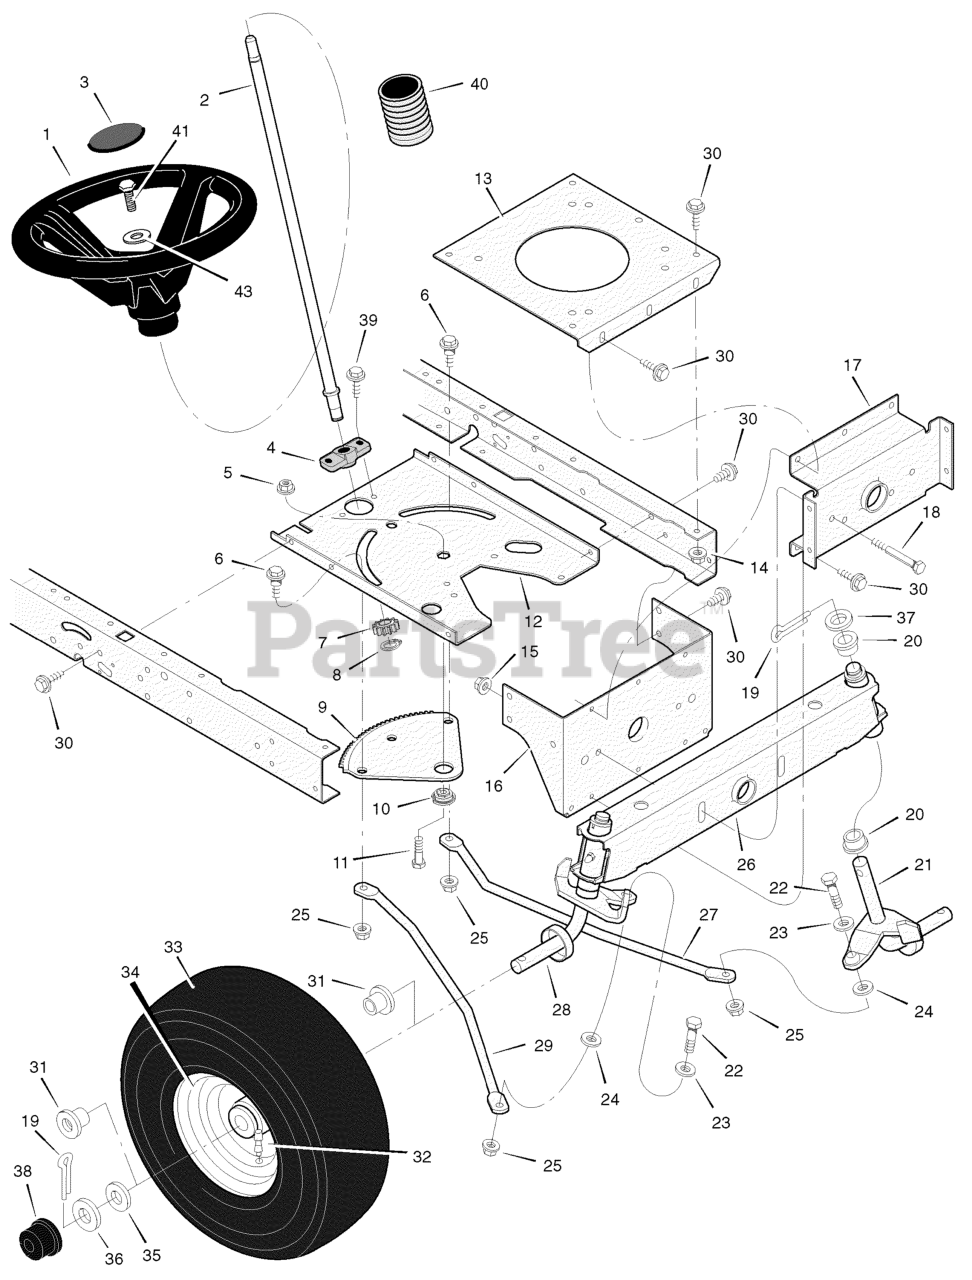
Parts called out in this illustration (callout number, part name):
1	Wheel, Steering
2	Post, Steering
3	Cap, Steering Wheel
4	Bearing, Lower
5	Nut, Flange
6	Bolt, Shoulder
7	Gear, Pinion
8	Ring, Snap
9	Gear, Sector
10	Bearing
12	Plate, Steering
13	Plate, Engine
14	Nut, Flange
15	Nut, Flange
16	Bracket, Hanger
17	Axle, Hanger
18	Bolt
19	Pin, Cotter
20	Bearing
21	Spindle Assembly, Left
22	Bolt
23	Washer
24	Washer
25	Nut, Flange
26	Axle Assembly
27	Drag Link, Left
28	Spindle Assembly
29	Drag Link, Right
30	Screw
31	Bearing, Wheel
32	Stem, Valve
33	Tire *
34	Wheel and Tire Assembly
35	Washer
36	Washer
37	Washer
38	Hub Cap
39	Screw
40	Bellows
41	Screw, Hex
43	Washer
